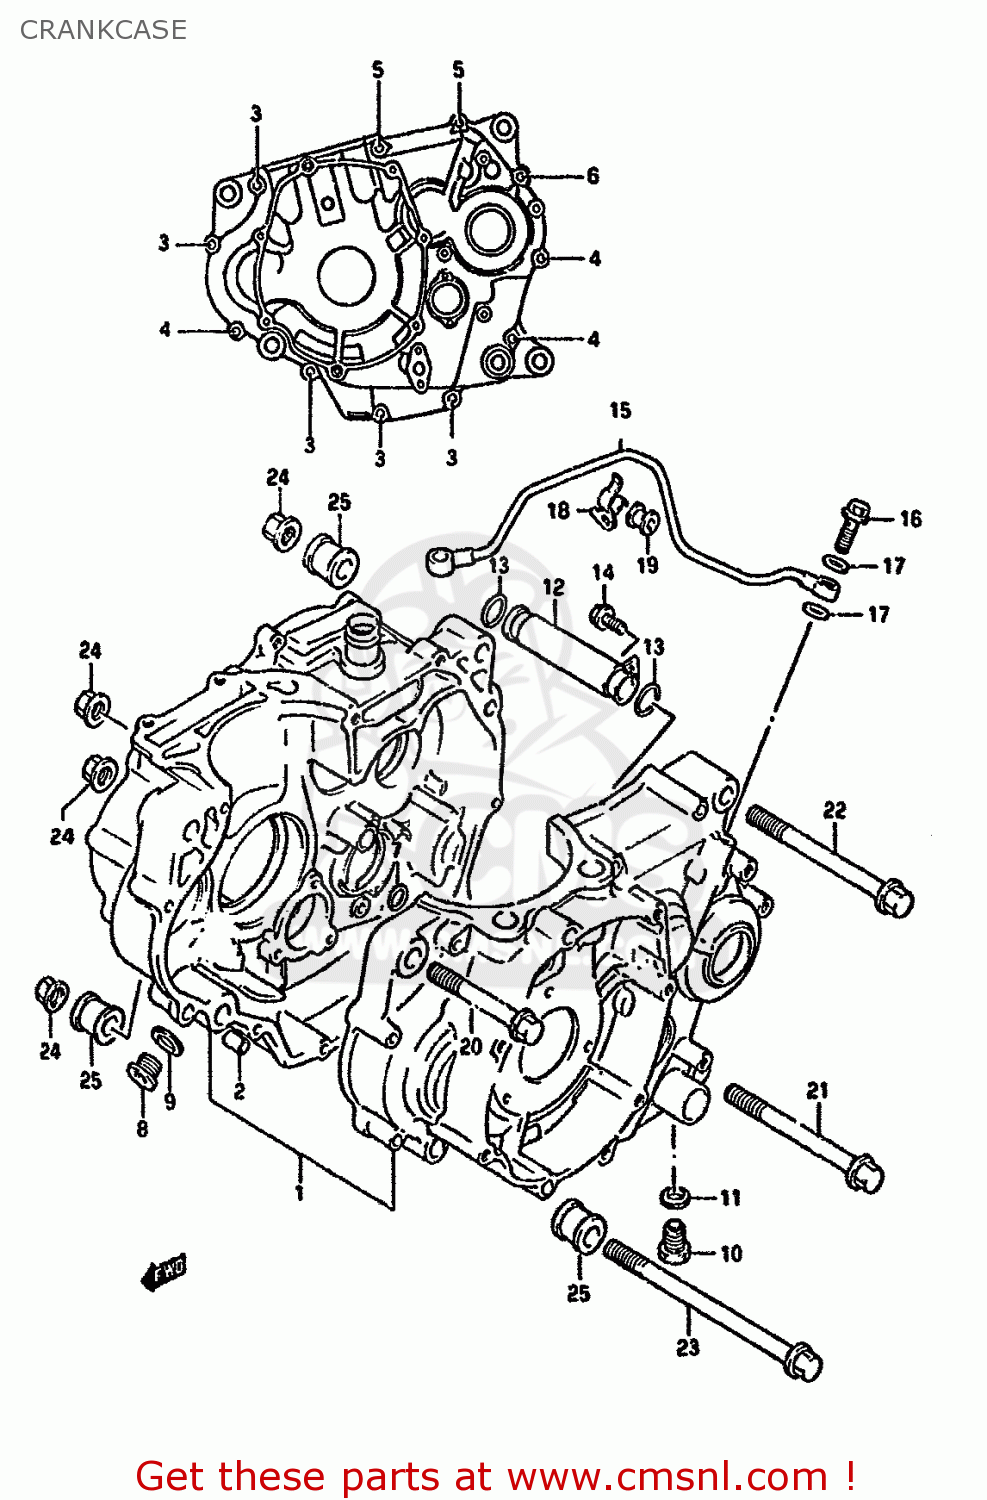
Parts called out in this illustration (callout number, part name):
1	CRANKCASE SET
2	PIN
3	BOLT
4	BOLT
5	BOLT
6	BOLT
7	O-RING
8	PLUG,14X12
9	GASKET(13.8X18.8X4.8) (NAS)
10	BOLT
11	GASKET(12.1X16.2X3.7) (NAS)
12	PIPE,T/M OIL INNER
13	O RING(D:2.4,ID:15.8)
14	BOLT
15	PIPE,T/M OIL OUTER
16	BOLT UNION
17	GASKET 8.2X14X1 (NAS)
18	CLAMP,OIL PIPE
19	CUSHION
20	BOLT 10X85
21	BOLT(10X101.5)
22	BOLT(10X115)
23	BOLT(10X143)
24	NUT
25	SPACER,ENGINE MOUNT
